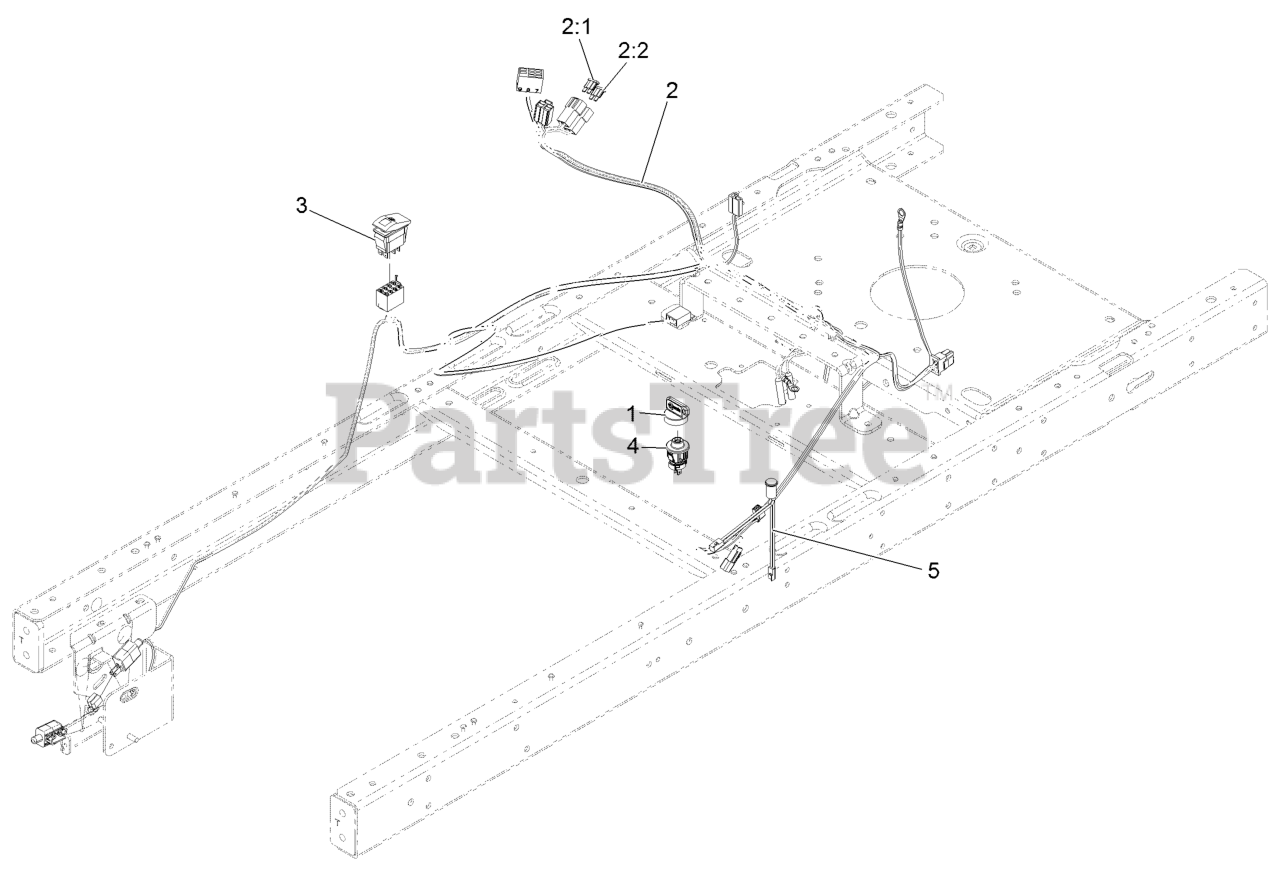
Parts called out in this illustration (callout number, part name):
1	KEY-IGNITION
2:1	FUSE-BLADE, 30 AMP
2:2	FUSE-BLADE, 25 AMP
3	SWITCH-ROCKER, (ON)-OFF-(
4	SWITCH-MOMENTARY, N.O.
5	LIGHT-INDICATOR
